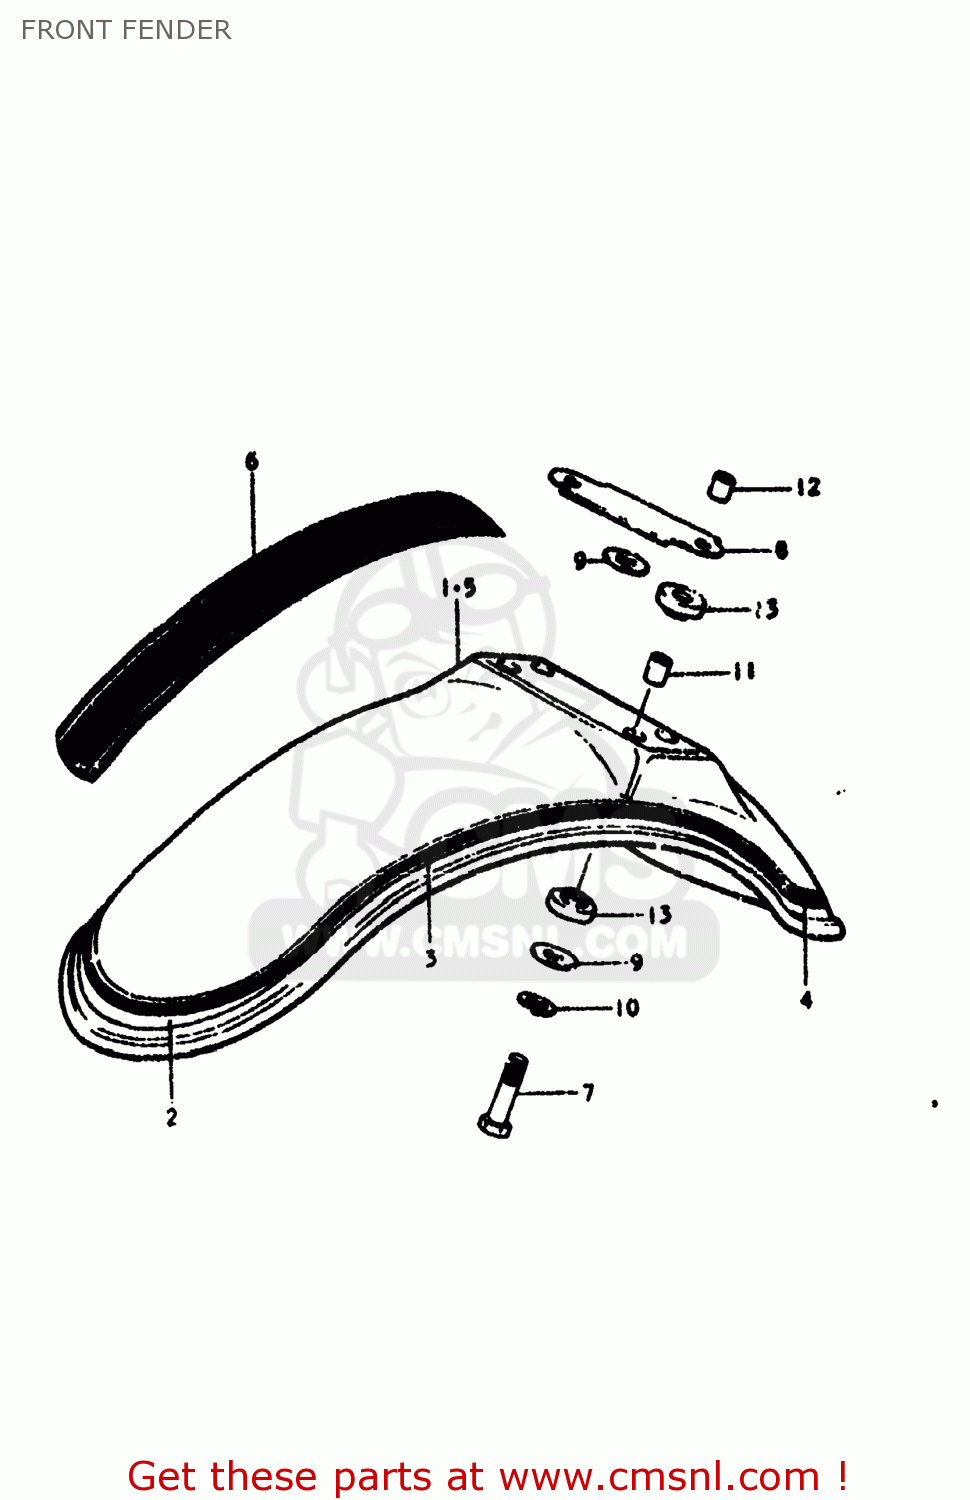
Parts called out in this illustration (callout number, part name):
1	FENDER,FRONT
2	TAPE,FRONT FENDER
3	TAPE,FRONT FENDER
5	FENDER,FRONT
7	BOLT
9	WASHER (6.5X24X1.2)
10	LOCK WASHER
11	SPACER
12	SPACER (6.5X10.5X13.5)
13	CUSHION
